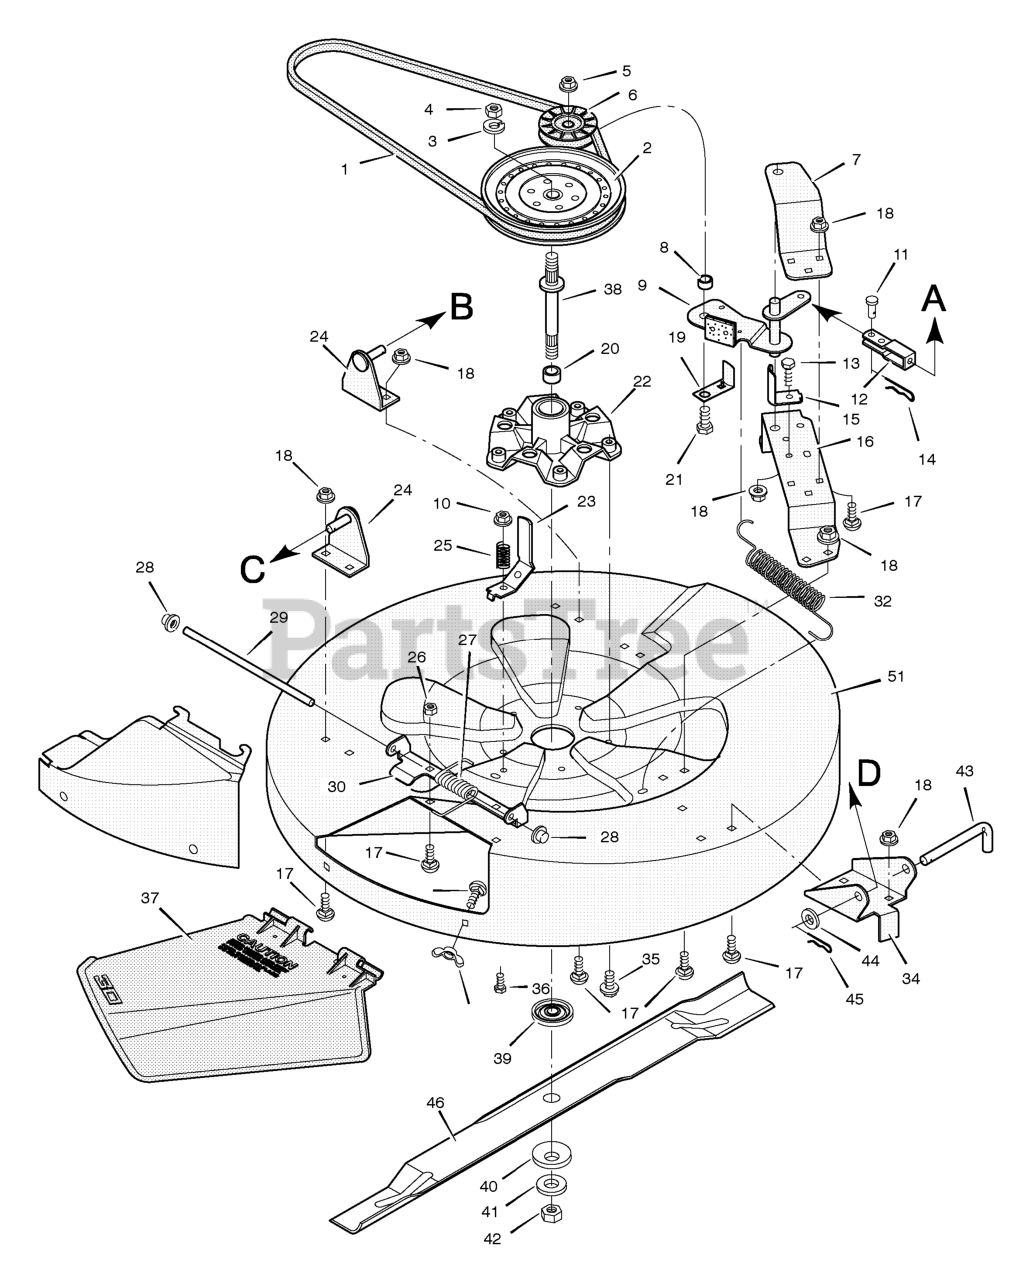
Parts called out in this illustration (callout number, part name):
1	Belt, Mower Drive
2	Pulley, Splined
3	Lockwasher
4	Locknut, Hex
5	Nut, Hex
6	Pulley, Idler
7	Bracket, Upper Idler
9	Assembly, Blade Idler
10	Locknut, Flange
11	Pin, Clevis
13	Bolt, Hex
14	Pin, Hair
15	Guide, Belt
16	Bracket, Lower Idler
17	Bolt, Carriage
18	Nut, Flange
19	Guide, Belt
21	Bolt, Hex
22	Housing, Mandrel
23	Guide, Belt
24	Bracket, Hanger
25	Spring, Compression
26	Nut, Hex
27	Spring - Torsional
28	Push On Cap
30	Hinge, Chute Deflector
32	Spring, Extension
34	Bracket, Front
36	Bolt, Hex
37	Deflector, Chute
38	Mandrel
39	Adapter, Blade
40	Washer, Belleville
41	Washer, Hardened
42	Nut, Hex
43	Pin, Pull
45	Pin, Hair
46	Blade, Standard
47	Blade, Mulcher
48	Plate, Mulcher
49	Bolt, Carriage
50	Wingnut
